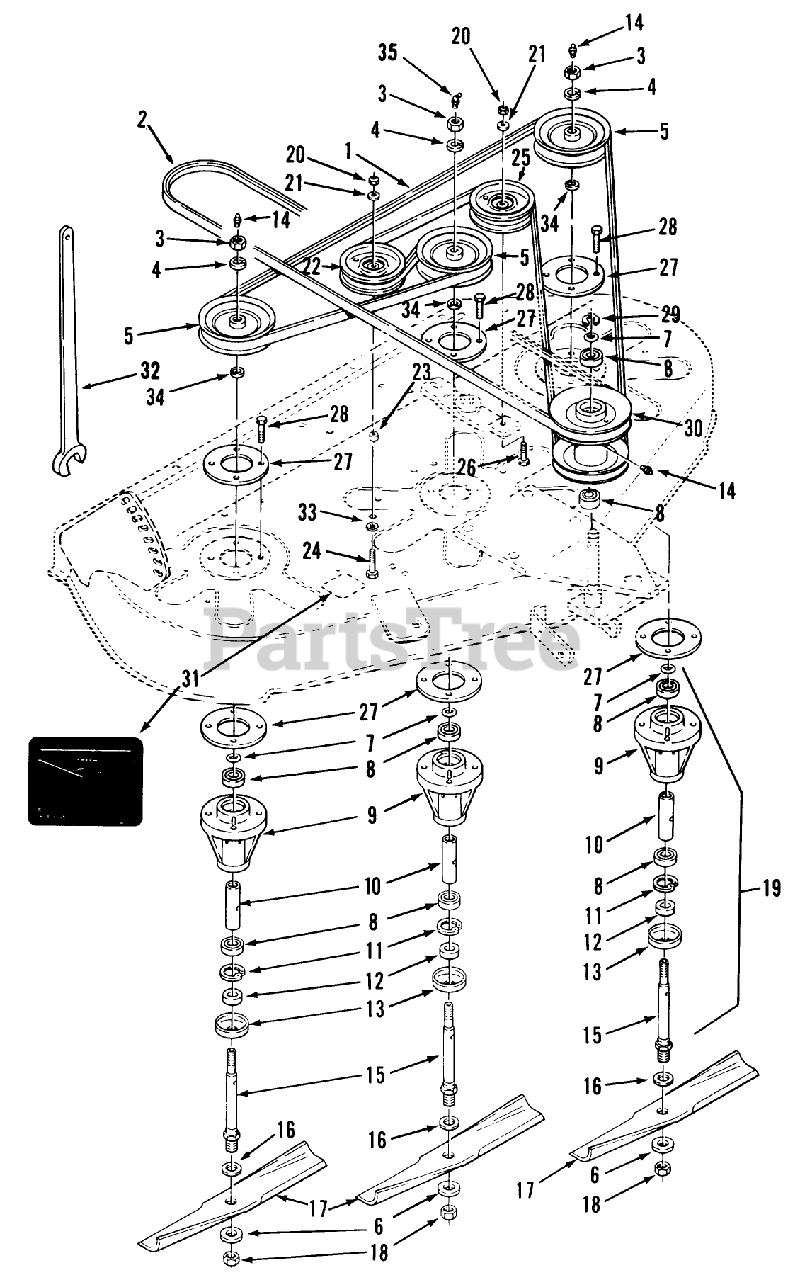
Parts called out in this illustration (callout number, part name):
1	V-BELT
2	V-BELT
3	NUT-JAM
4	WASHER-LOCK
5	PULLEY-SPINDLE
6	WASHER-FLAT
7	O RING
8	BEARING-BALL
9	HOUSING-SPINDLE
11	Ring-Snap
12	SPACER-BLADE
13	CUP-SPINDLE
14	FITTING-GREASE
15	SHAFT-SPINDLE
16	Washer
17	BLADE KIT
18	NUT-JAM
19	Spindle Assembly
20	NUT-LOCK, NI
21	WASHER-FLAT
22	Pulley-Idler
23	SPACER
24	SCREW-CARR
25	PULLEY-FLAT IDLER
26	SCREW-HH
27	SPACER-SPINDLE
28	SCREW-HH
29	RETAINING RING
30	PULLEY-COUNTER SHAFT
31	DECAL-BELT INSTALL
32	Spindle Wrench
34	Washer
35	FITTING-GREASE
